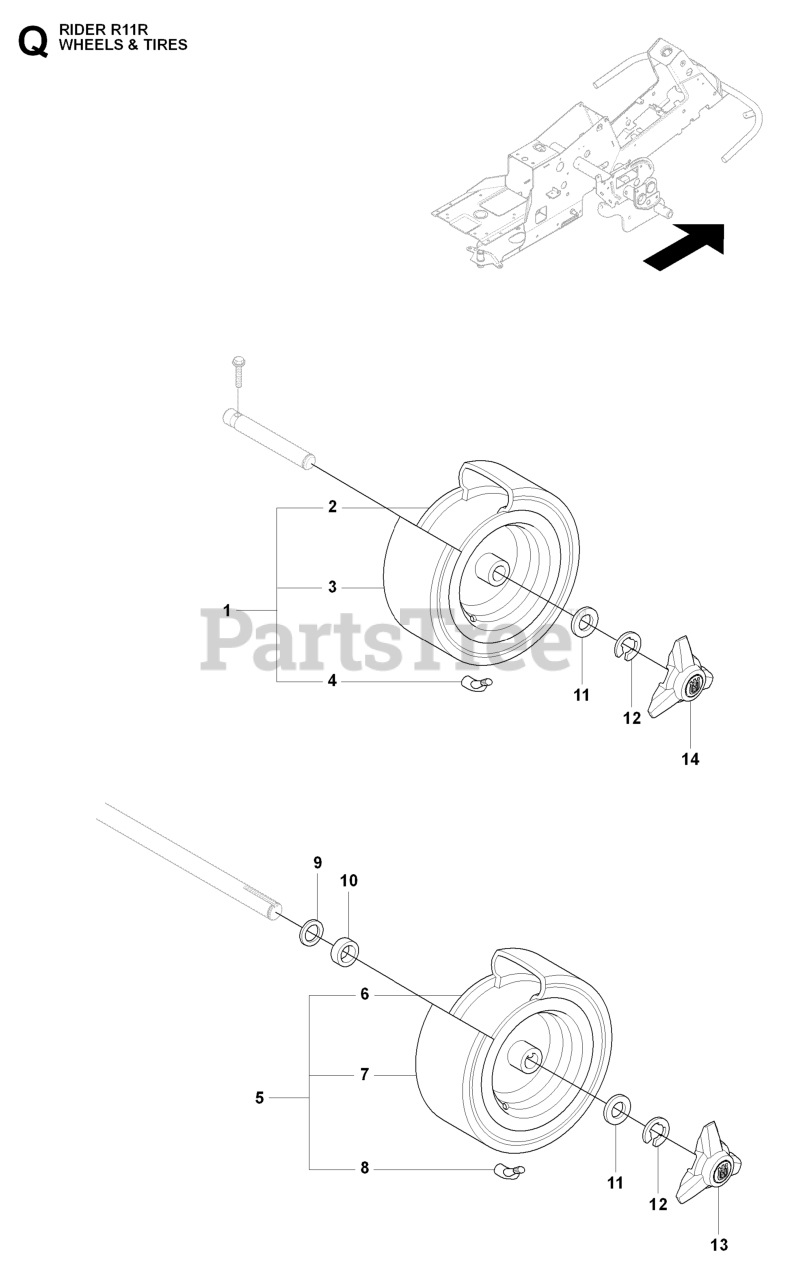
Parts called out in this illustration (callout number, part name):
5	WHEEL
6	RP RIM
12	RETAINING RING
